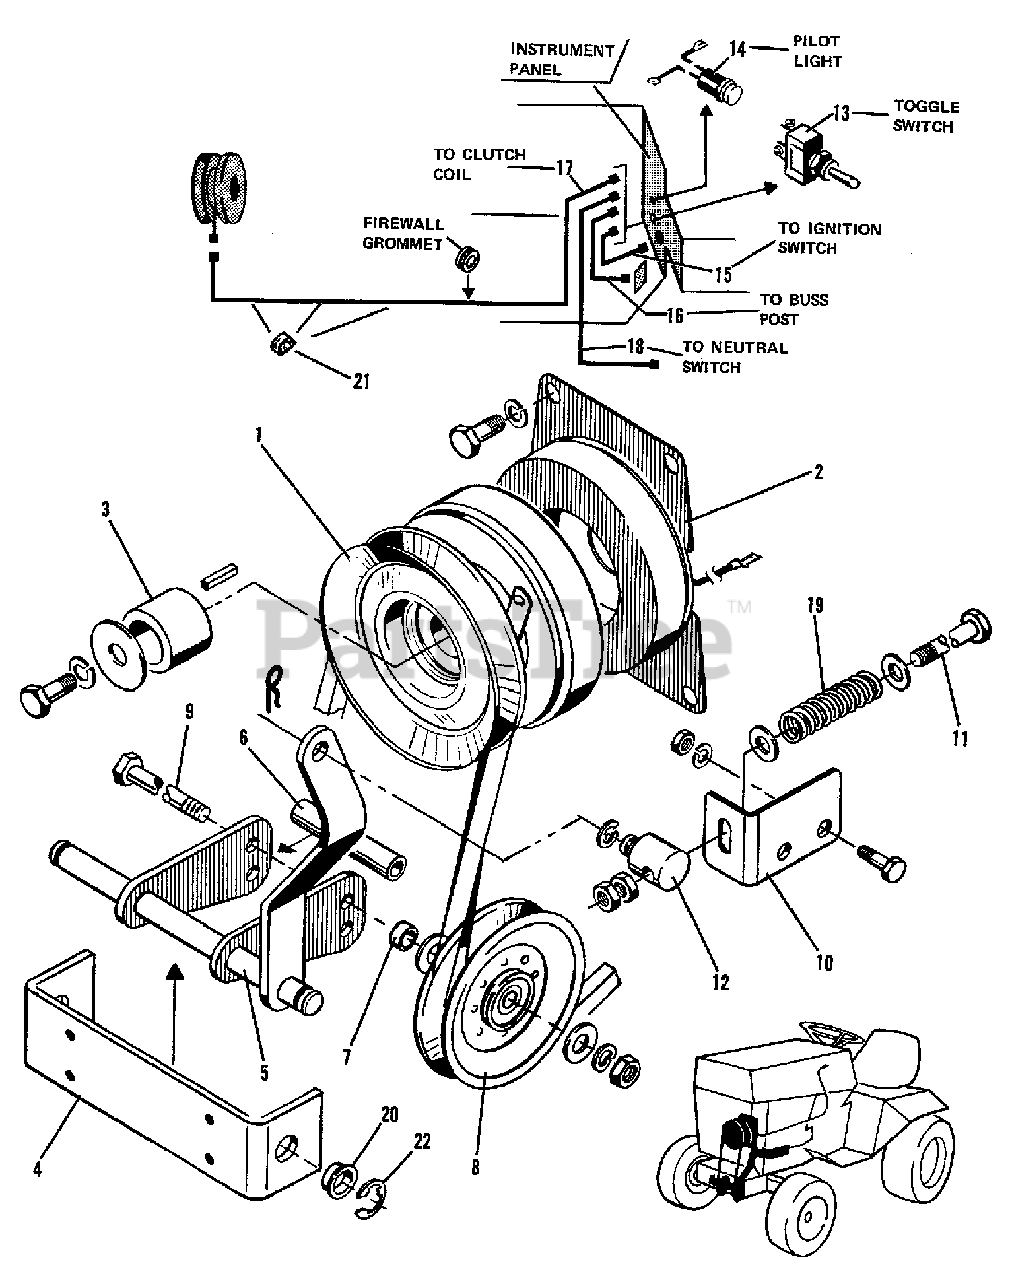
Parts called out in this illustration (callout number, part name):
1	*HUB, Clutch
2	*COIL, Clutch
3	CAPSCREW, 7/16 NF x 1-1/4
3	WASHER, Plain, 1/2 x 1-1/2 x 10 Ga.
3	LOCKWASHER, 7/16
4	BRACKET, Idler Support
4	CAPSCREW, 5/16 NC x 3/4
4	LOCKWASHER, 5/16
4	NUT, 5/16 NC
5	CLEVIS ASSEMBLY, P.T.O. Idler
6	SPACER, Idler
8	PULLEY, Idler
9	CAPSCREW, 3/8 NC x 6-1/4
9	WASHER, Plain, 7/16 x 1 x 14 Ga.
9	LOCKWASHER, 3/8
9	NUT, 3/8 NC
10	BRACKET, Idler
10	CAPSCREW, 3/8 NC x 1
10	LOCKWASHER, 3/8
10	NUT, 3/8 NC
11	BOLT, Special
11	WASHER, Plain, 13/32 x 7/8 x .083
11	NUT, 3/8 NC
12	RING, Snap
13	*SWITCH, Toggle
14	*LIGHT, Pilot
15	*LEAD, Ignition Switch To P.T.O. Switch
16	*LEAD, Buss Post To Switch
17	*LEAD, Switch to P.T.O. Clutch
18	*LEAD, Electric P.T.O. Interlock
20	BUSHING, Nylon
21	CLIP, Closed, #3
22	RING, Snap
